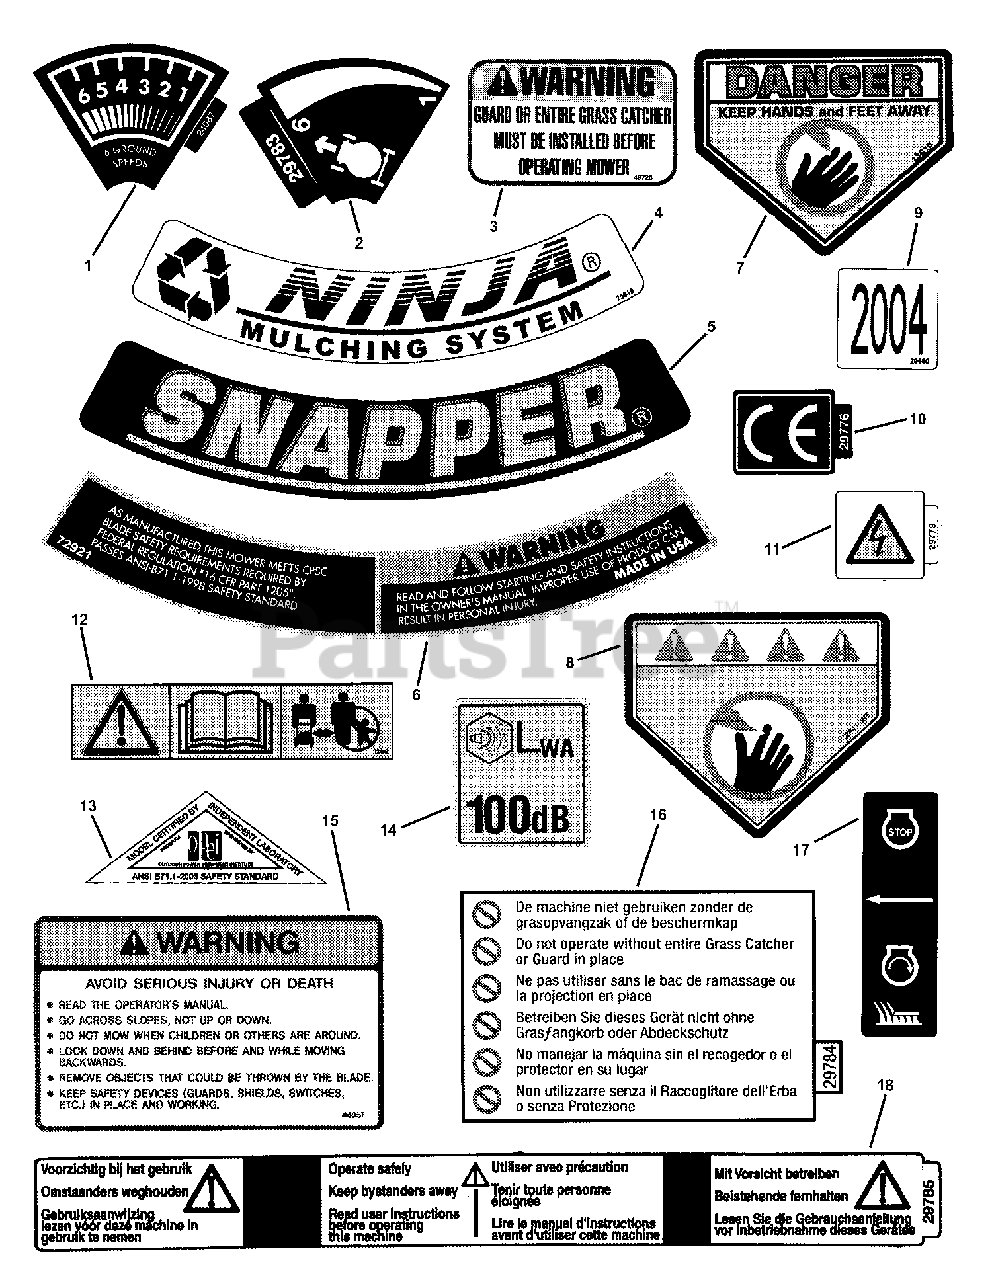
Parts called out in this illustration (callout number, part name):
1	DECAL, Speed Sector
2	DECAL, Speed Sector Int'l Symbol
3	DECAL, Chute/Deflector
4	DECAL, Ninja
5	DECAL, SNAPPER
6	DECAL, Warning (Deck)
7	DECAL, Danger, Cut Finger
8	DECAL, Warning (Euro)
9	DECAL, 2004 Year of Mfg.
10	DECAL,Euro Community (CE)
11	DECAL, Spart Plug International Symbol
12	DECAL, Caution, Symbols
13	DECAL, OPEI Walk/Ride
14	DECAL, Noise (European)
15	DECAL, Warning
16	DECAL, Deck/Chute International Warning
17	DECAL, OPC Bail (International Symbol)
18	DECAL, Operator Safety
